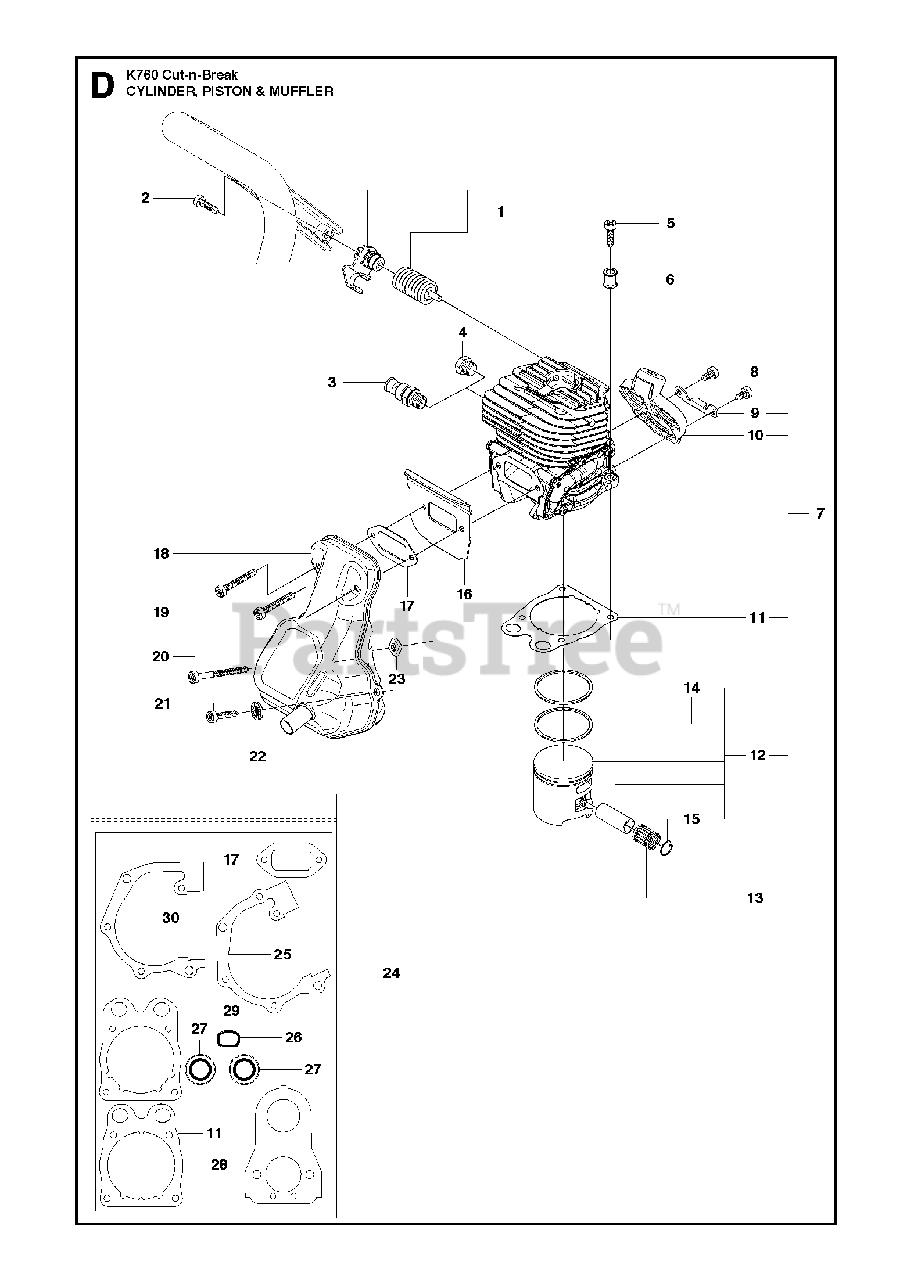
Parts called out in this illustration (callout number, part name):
1	ANTIVIBRATION ELEMENT
2	SCREW ITXSCM
3	DECOMPRESSION VALVE
5	SCREW ITXSCM
7	CYLINDER ASSYIncl. 8 - 13
8	SCREW ITXSCM
10	PLATE
12	PISTON ASSYIncl. 13 - 15
13	NEEDLE BEARING
14	PISTON RING
16	COOLING AIR CONDUCTOR
17	GASKET
18	MUFFLER ASSY
19	SCREW ITXSCM
20	SCREW ITXSCM
21	SCREW ITXSCM
24	GASKET KITIncl. 11, 17, 25 - 30
27	SEALING RINGBlue
